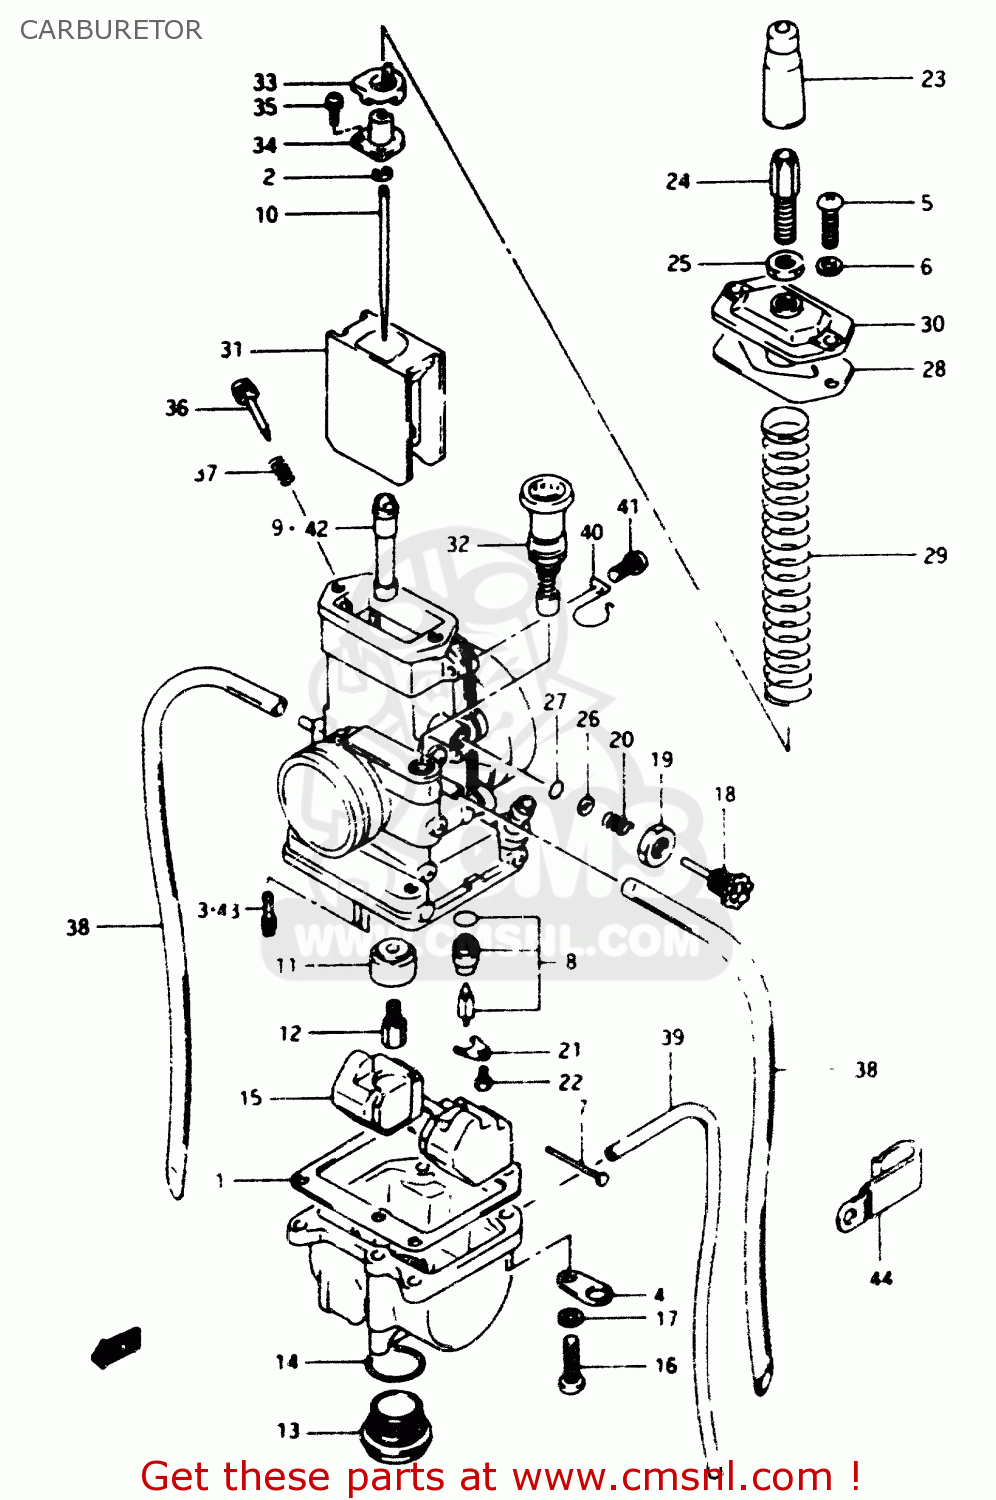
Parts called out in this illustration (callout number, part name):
1	GASKET,FLOAT CAHMBER (NAS)
2	CLIP
3	JET,PILOT(30)
4	PLATE,CARBURETOR
5	SCREW
6	WASHER,LOCK
7	PIN,FLOAT
8	VALVE ASSY,NEEDLE
9	JET,NEEDLE(P-4)
10	NEEDLE,JET(5DP39-4)
11	RING
12	JET,MAIN (210)
13	PLUG
14	O RING
15	FLOAT
16	SCREW
17	WASHER,LOCK
18	ADJUSTER,THROTTLE STOP
19	NUT
20	SPRING
21	PLATE
22	SCREW
23	CAP,CABLE ADJUSTER
24	ADJUSTER,CABLE
25	NUT
26	WASHER
27	O RING
28	GASKET,CARBURETOR TOP (NAS)
29	SPRING
30	CAP,CARBURETOR TOP
31	VALVE,THROTTLE
32	PLUNGER ASSY,STARTER
33	RING
34	JOINT
35	SCREW
36	SCREW,AIR
37	SPRING
38	HOSE(3.5X6.5X600)
39	HOSE(3X5X600)
40	CLIP
41	SCREW
42	JET,NEEDLE,P-2
43	JET,PILOT(25)
44	CLAMP
